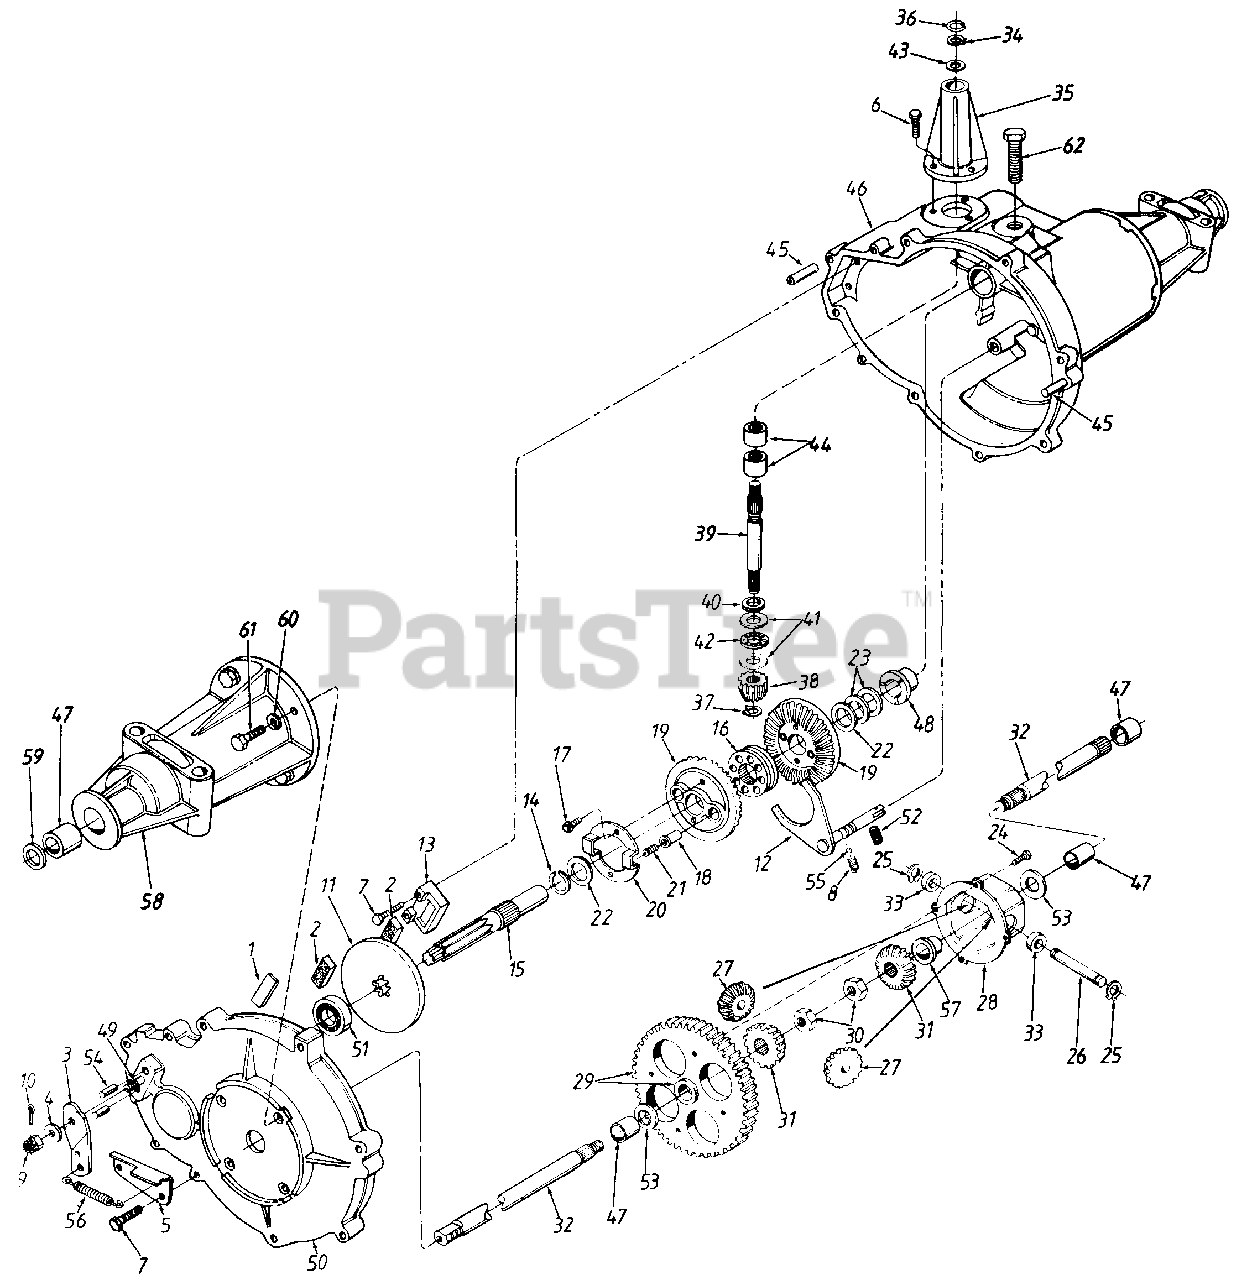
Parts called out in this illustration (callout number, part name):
1	Puck Plate
2	Brake Puck
3	Actuating Arm
4	Fl-Wash. 11/32" I.D. x 7/8" O.D.
5	Brake Stop Brkt.
6	Hex Bolt 1/4-20 x .62" Lg.
7	Hex Tap Scr. 1/4-20 x 1.25" Lg.
8	Spring Detent
9	Castle Nut 5/16-24 Thd.
10	Cotter Pin 3132" Dia. x 1" Lg.
11	Brake Disc
12	Shifter Ass'y.
13	Brake Puck Holder
14	Retaining Ring
15	Shaft Drive
16	Shift Collar
17	Hex Wash. Hd. Tap Scr. 1/4-20 x.38" Lg.
18	Drive Pin
19	Bevel Gear Ass'y.
20	Spring Retaining Plate
21	Drive Spring
22	Fl-Wash. .915" I.D. x 1.5" O.D.
23	Fl-Wash. .915" I.D. x 1.37" O.D.
24	Pan Hd. Scr. 1/4-20 x .5" Lg.
25	Snap Ring
26	Cross Shaft
27	Miter Gear 15T
28	Differential Can Assembly
29	Differential Gear Ass'y. w/ Bearing
30	Hex Ins. L-Nut 1/2-20 Thd.
31	Miter Gear
33	Differential Thrust Spacer
34	Retainer Ring
35	Input Bearing Housing
36	Wire Ring
37	Retaining Ring
38	Pinion Input 14T
39	Input Shaft
40	Seal 5/8" I.D.
41	Thrust Wash. .621" I.D. x 1.12
42	Thrust Bearing
43	Fl-Wash. 5/8" I.D. x 1.25" O.D.
44	Needle Brg. 5/8" x 1/2" Lg.
45	Dowel Pin
46	R.H. Housing
47	Sleeve Bearing 3/4" I.D.
48	Flange Bearing .906" I.D.
49	Sq. Head Bolt 5/16-24 Thd.
50	L.H. Housing
51	Ball Bearing .669" I.D.
52	Set Screw 5/16-18 x 3/8" Lg.
53	Fl-Wash. .76" I.D. x 1.5" O.D.
54	Brake Actuating Pin
55	Ball Detent
56	Ext. Spring 1.14" Lg.
57	Differential Flange Brg.
58	Axle Horn Ass'y.
59	Oil Seal 3/4" I.D.
60	L-Wash. 3/8" I.D. (H.D.)
61	Hex Bolt 3/8-24 x 1.25" Lg.
62	Nylon Hex Cap Scr. 1/2-13 x .75" Lg.
